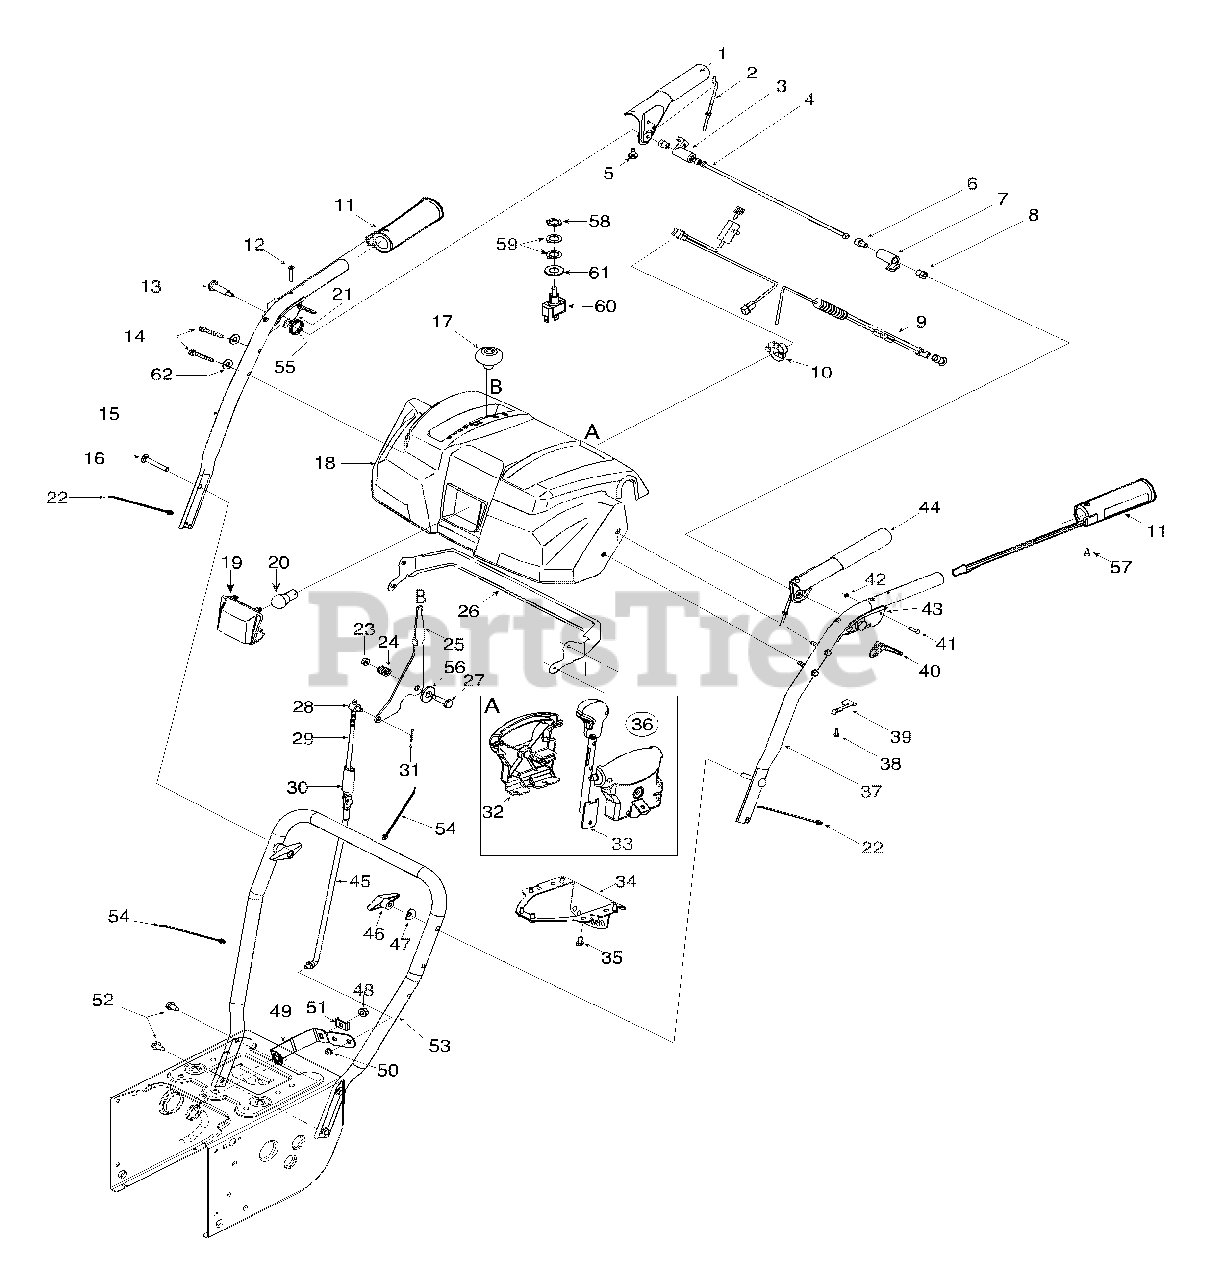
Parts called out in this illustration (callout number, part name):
1	Handle Engagement Assembly RH
2	Cable Z- Fitting
3	Lock Plate
4	Pivot Rod
5	Rubber Bumper
6	Screw, 1/4-20 x.375
7	Clutch Lock Cam
8	Shoulder Nut, 1/4-20
9	Heated Grips Harness
10	Light Socket
11	Heated Grip
12	Screw, #10-24 x 0.375
13	Shoulder Screw, 1/4-20 x 1.345
14	Screw, 1/4-20 x 1.750
16	Carriage Screw, 5/16-18 x 2.25
17	Shift Knob
18	Handle Panel Assembly
19	Lens
20	Lamp
21	Handle Clutch Lock - RH
22	Cable Tie
23	Flange Lock Nut, 1/4-20
24	Compression Spring
28	Ferrule
29	Upper Shift Rod
30	Shift Rod Connector
31	Hairpin Clip
32	Kit, Joystick Housing w/Fasteners
33	Kit, Knob Assembly w/ Trigger
35	Hi-Lo Screw, 1/4-15 x 0.5
36	4-Way Chute Control (tm)
38	Screw, #8-16 x 0.50
39	Clutch Lock Spring
40	Steering Control
43	Handle Clutch Lock - LH
44	Handle Engagement Assembly LH
45	Lower Shift Control Rod
46	Handle Knob Assembly
47	Saddle Washer
48	Flange Lock Nut, 5/16-18
50	Speed Nut
51	Shift Bracket Spacer
52	AB Screw, 5/16-12 x 0.75
54	Cable Tie
55	Torsion Spring
56	Flat Washer
57	Screw, #10-16 x.625
58	Jam Nut, 15/32-32
59	Toggle Switch Lock Ring
60	2 Pos., Single Throw Togg. Switch
61	Flat Washer
62	Washer, Flat,.25 x.630 x.0515
